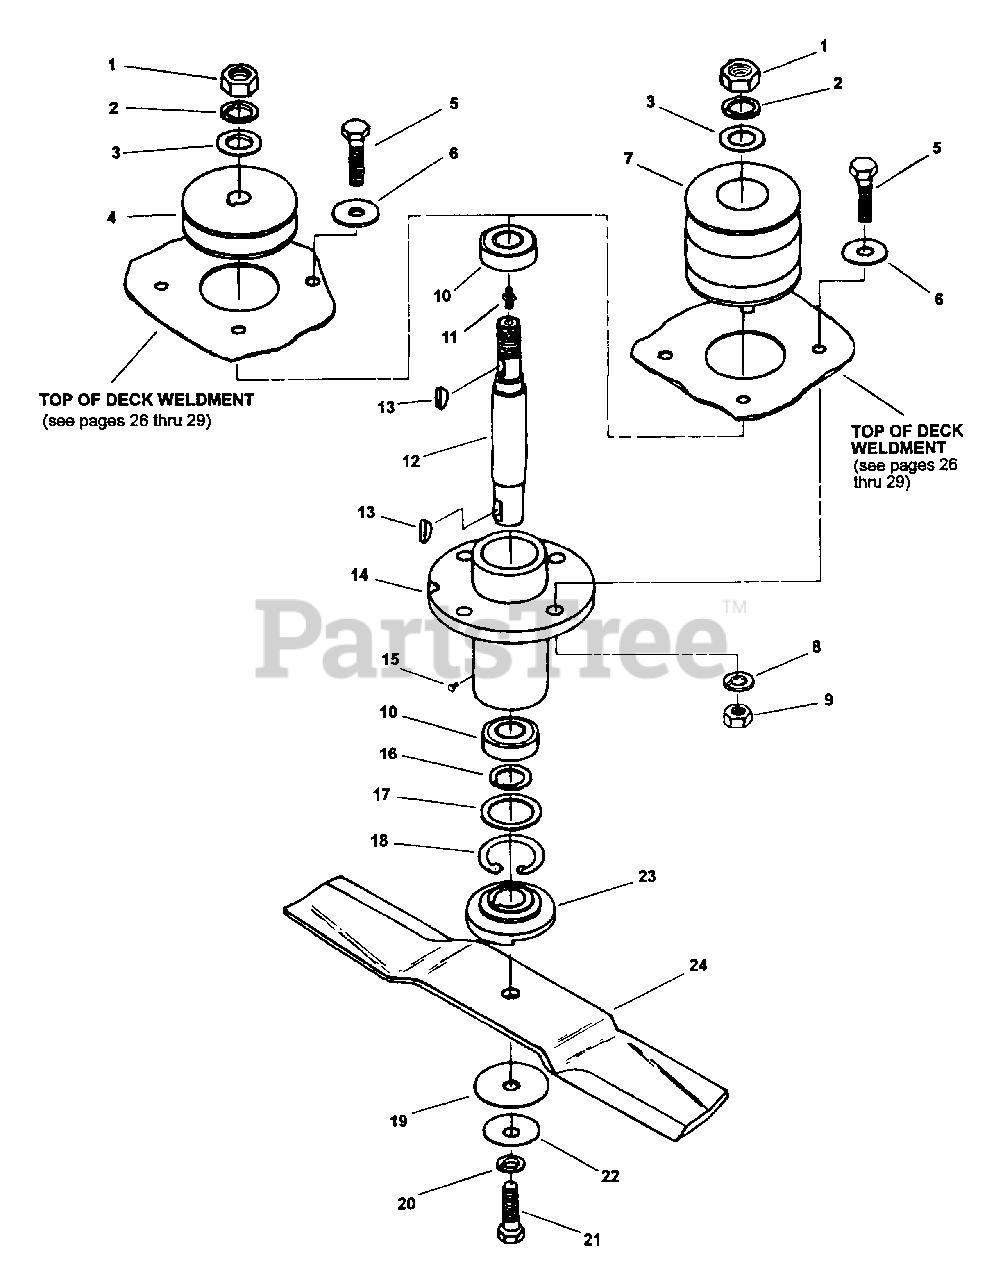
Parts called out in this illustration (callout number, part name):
1	NUT, 3/4-16 Hex Jam
2	LOCKWASHER, 3/4" STD. SPLIT SPRING
3	WASHER, 3/4" FLAT TYPE B NARROW
4	PULLEY, 1 GROOVE 4" O.D., SPLIT STEEL
5	BOLT, 3/8-24 X 1-1/2" GR. 5
6	SPINDLE SPACER REINFORCEMENT
7	PULLEY, 2 GROOVE, SPLIT STEEL
8	LOCKWASHER, 3/8" HEAVY SPRING TYPE
9	LOCKNUT, HEX. 3/8" HEAVY SPRING TYPE
10	BEARING, #6205-2RS
11	GREASE FITTING, 1/4-28 SELF TAP
12	SPINDLE SHAFT
13	WOODRUFF KEY, UASS #806, 1/4 X 3/4"
14	SPINDLE HOUSING
15	SCREW RND. DR. #4 X 3/16"
16	ARBOR SPACER
17	WASHER SEAL
18	SNAP RING, INTERNAL, 52 MM BORE
19	WASHER, FLAT .515 I.D. X 2.50 O.D.
20	LOCKWASHER, 1/2" STD. SPLIT SPRING
21	BOLT, 1/2-13 X 1-1/2" GR. 5
22	WASHER, 1/2" CUPPED
23	BLADE SPACER
24	BLADE, LOW LIFT, 15" CUT, 42" DECK
